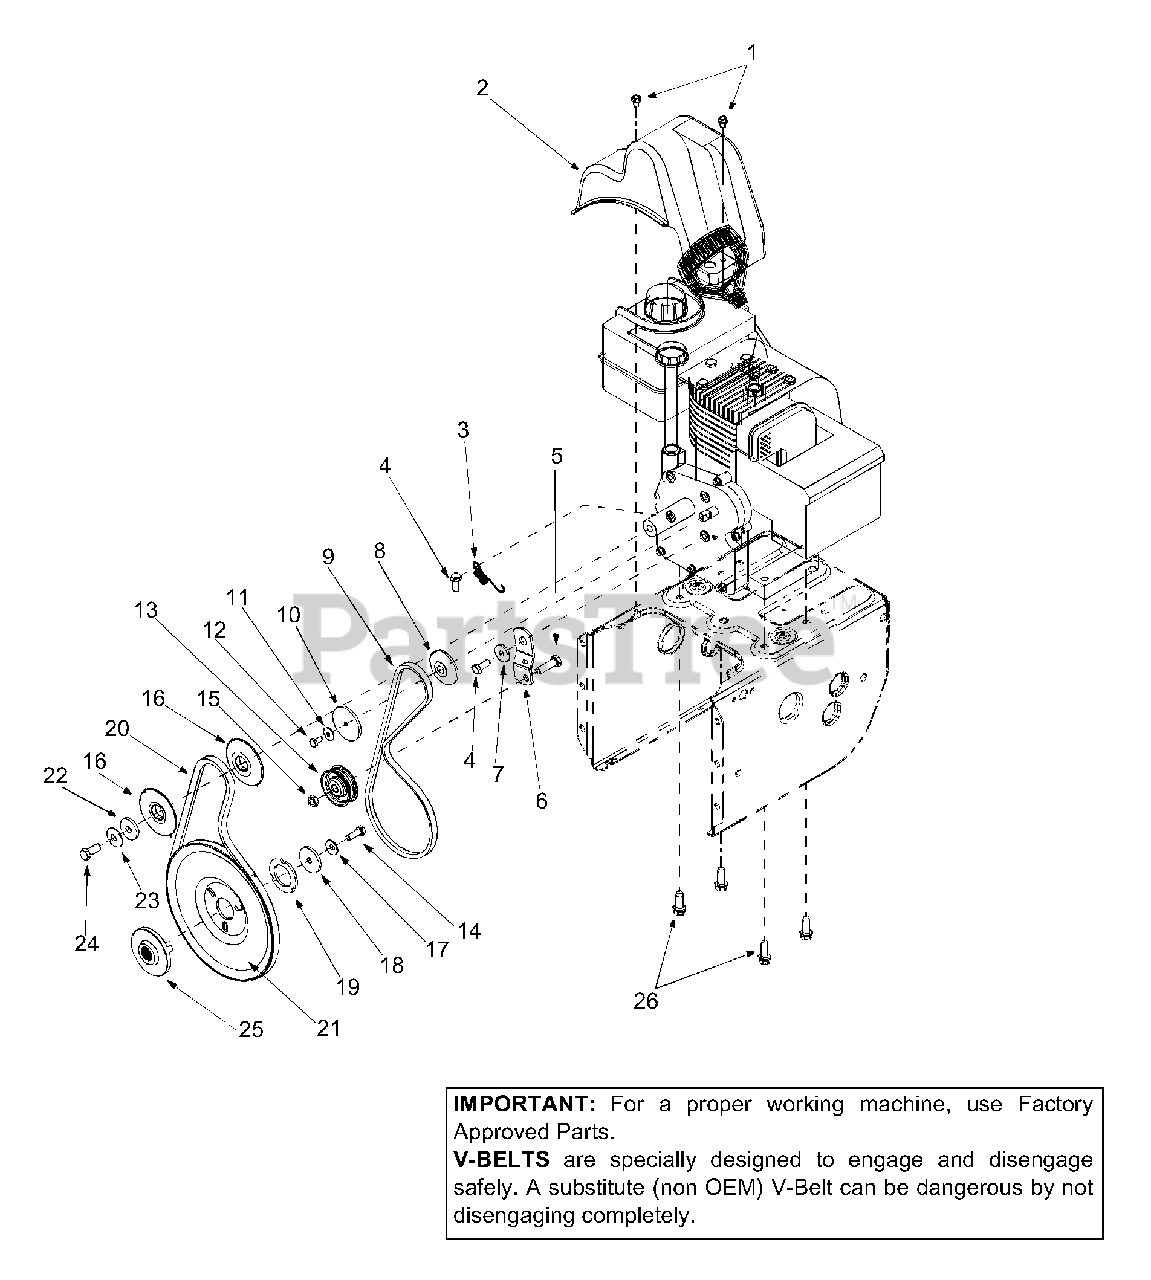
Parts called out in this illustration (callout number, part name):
1	Hex Washer Screw 1/4-20 x.5
2	Belt Cover
3	Extension Spring
4	Hex Screw 5/16-24 x.75
5	Hex Cap Screw 3/8-16 x 1.25
8	Pulley Half
9	V-Belt
10	Pulley Half
11	Bell Washer
12	Hex Cap Screw 1/4-28 x.50
13	Flat Idler
14	Lock Cap Screw 5/16-24
15	Lock Jam Nut 3/8-16
16	Pulley Half
17	Bell Washer
18	Flat Washer
19	Washer
20	Belt
21	Auger Pulley
22	Flat Washer
23	Bell Washer
24	Hex Cap Screw 3/8-24
25	Pulley
26	Hex Washer Screw 3/8-16 x 1.0
